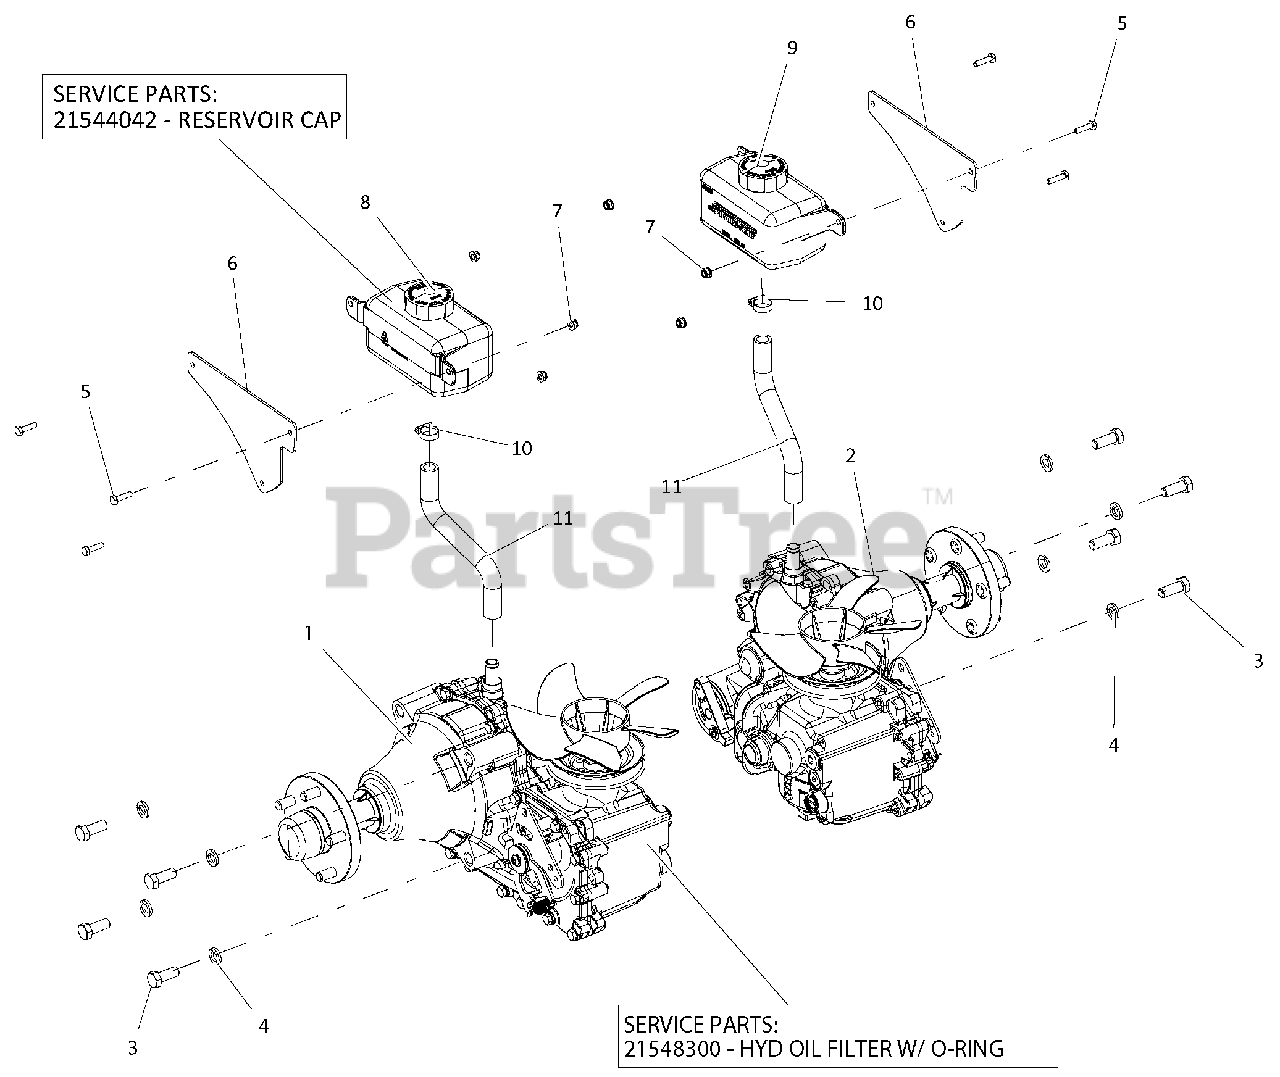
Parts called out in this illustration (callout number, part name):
1	TRANS, R.H. HG ZT-5400
1	SERVICE PART: HYD OIL FILTER W/ O-RING
2	TRANS, LH HG ZT-5400
3	BLT-HEX .50-13X1.25 GR5 YWZC
4	WSHR-LK .50X.125 REG YWZC
5	BLT-HEX .25-20X1.00 GR5 YWZC
6	PLATE, HYDRO OVERFLOW TANK MTG
7	NUT-LK-NYL-FLG .25-20 YWZC
8	TANK, HYD 1000ML
8	SERVICE PART: RESERVOIR CAP
9	TANK, HYD 1000ML
10	CLAMP, .88 DIA HOSE
11	HOSE, HYDRO OVERFLOW
